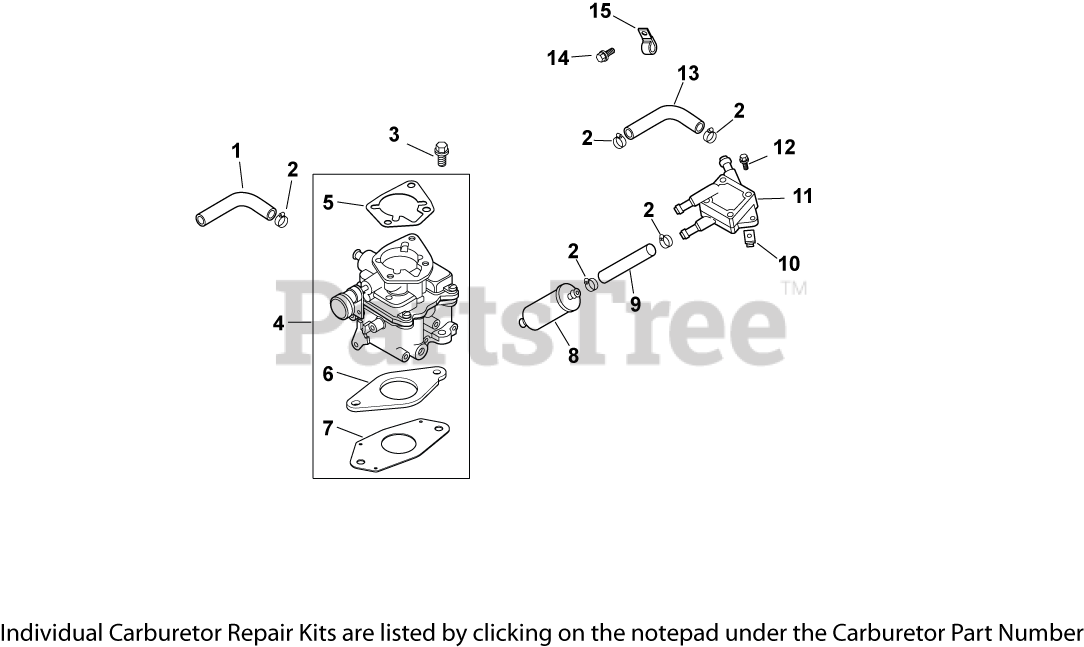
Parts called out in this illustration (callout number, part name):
1	HOSE, FUEL LOW-PERMEATION
2	CLAMP, HOSE (KM)-USE 25 237 31-S
3	SCREW, FLG M6X1.0X30
4	KIT, CARBURETOR W/GASKETS KSF
5	GASKET, AIR CLEANER BASE
6	GASKET, CARBURETOR
7	GASKET, CARBURETOR
8	FILTER, FUEL
9	HOSE,LW PERM.FUEL 24.00"-USE 25 111 81-S
10	NUT, PLASTIC - BLACK
11	PUMP, FUEL
12	SCREW, TAP M6X1.7X18
13	LINE, FLEXIBLE FUEL 15 1/2"
14	SCREW, FLG M6X1.0X12
15	CLIP, CABLE
